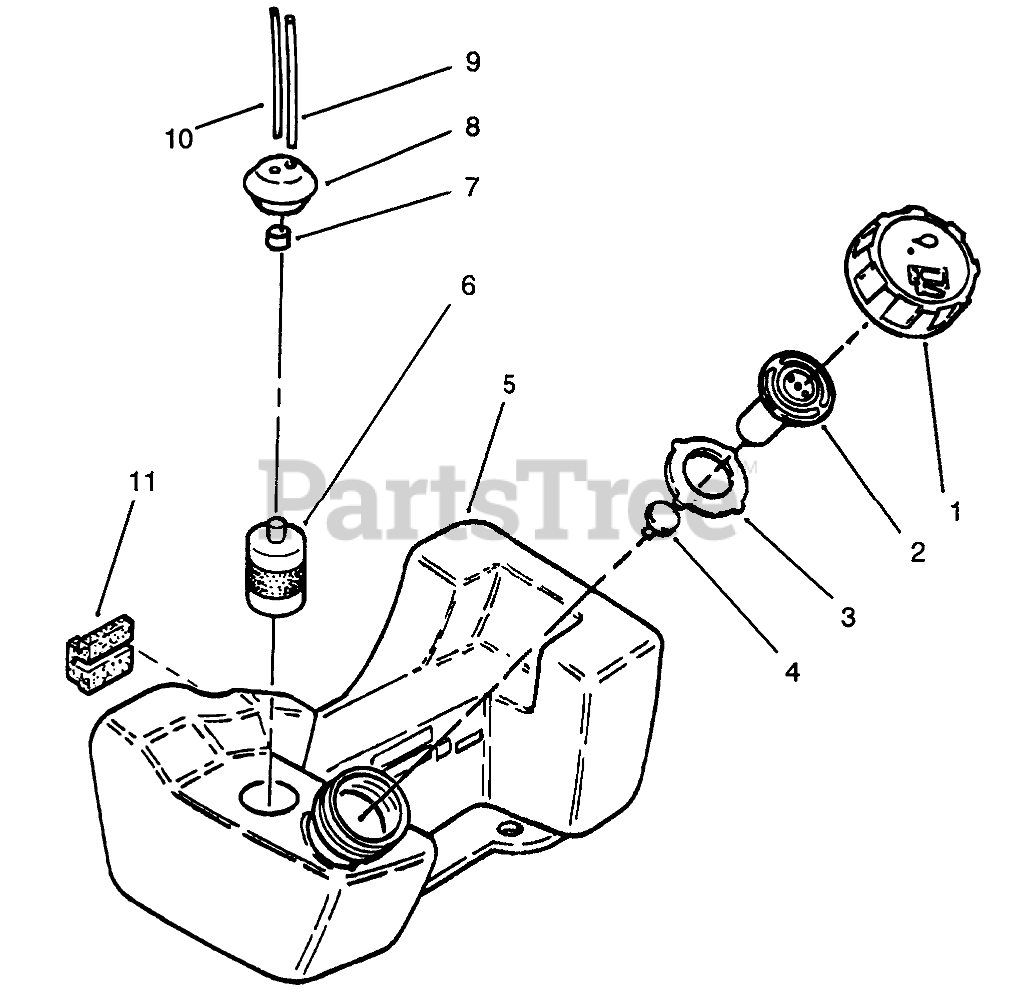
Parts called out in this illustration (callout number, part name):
1	FUEL TANK CAP
2	BREATHER VALVE
3	PACKING
5	Tank Assembly-Fuel (Incl. Ref. #1-4 & 10)
6	FUEL FILTER
7	COLLAR
8	FUEL TANK GROMMET
9	FUEL TUBE
10	RETURN FUEL HOSE
